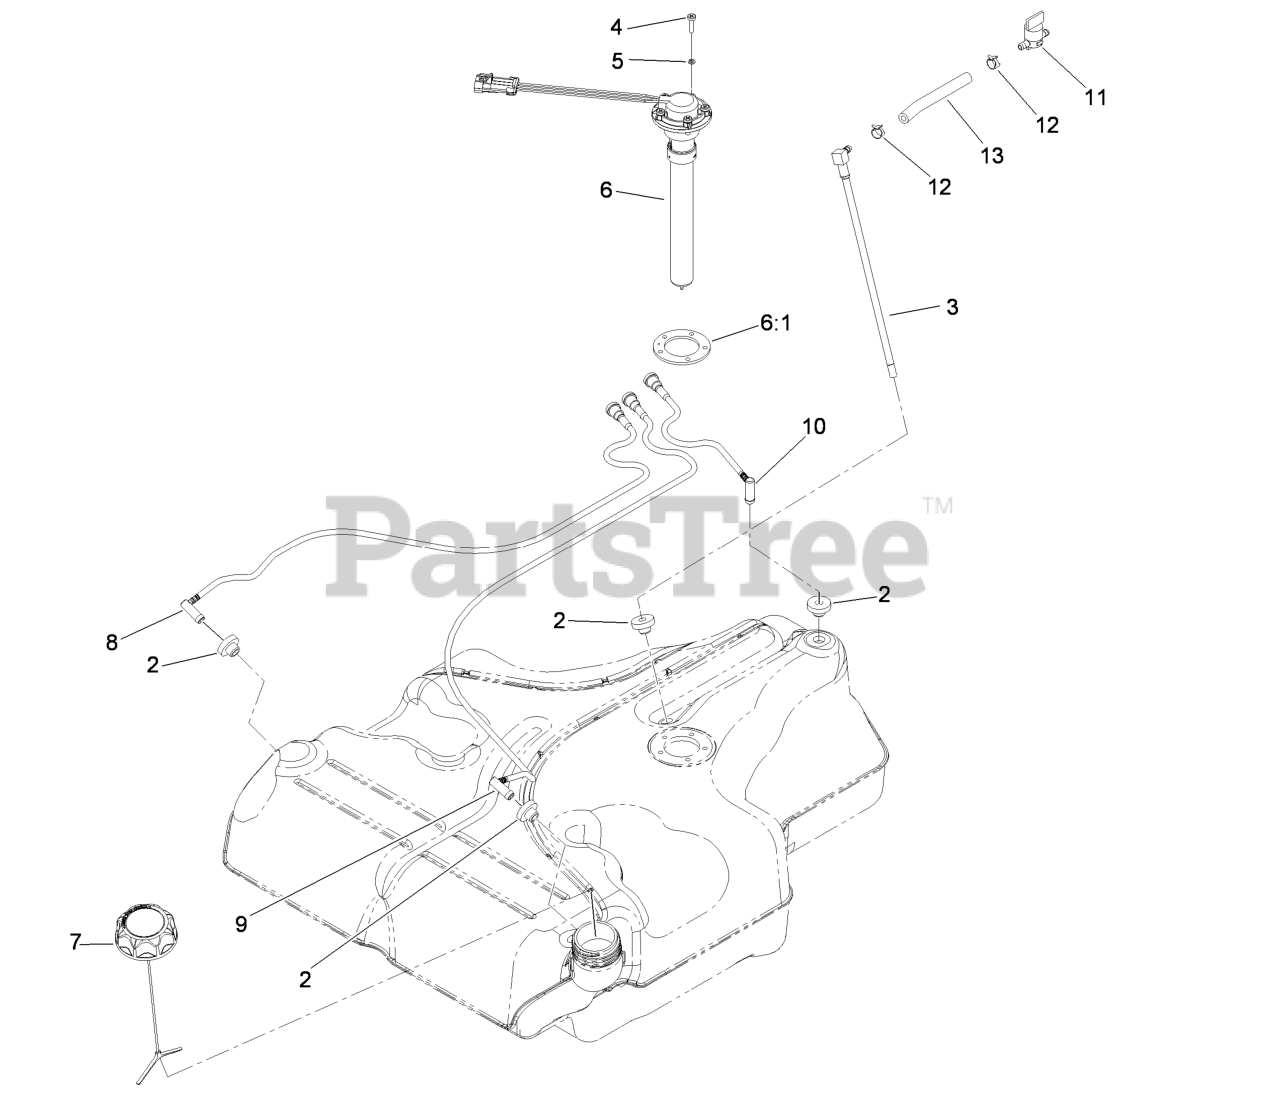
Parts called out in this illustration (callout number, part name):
2	BUSHING
3	FUEL LINE KIT (WITH GROMMET)
4	SCREW-PAN
5	WASHER-LOCK
6:1	GASKET-SENDER, FUEL
8	RH VENT LINE KIT (WITH GROMMET)
9	LH VENT LINE KIT (WITH GROMMET)
10	REAR VENT LINE KIT (WITH GROMMET)
11	VALVE-FUEL
12	CLAMP-HOSE
13	HOSE-FUEL
